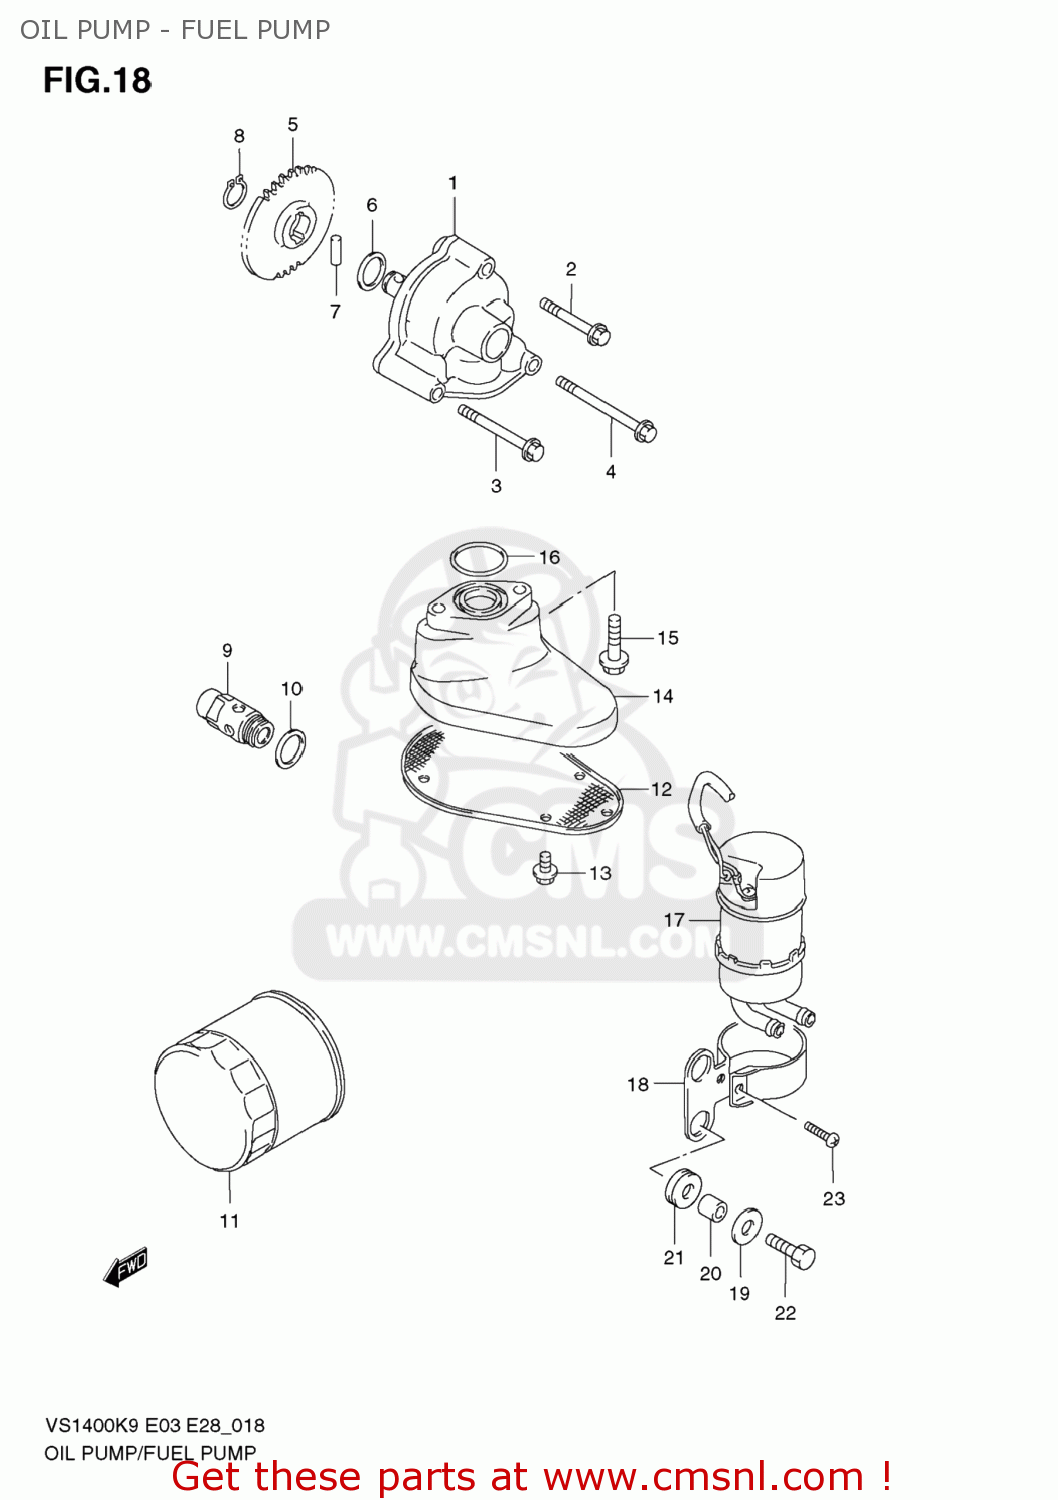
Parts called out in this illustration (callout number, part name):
1	PUMP ASSY,ENGINE OIL
2	BOLT
3	BOLT
4	BOLT
5	GEAR,OIL PUMP DRIVEN
6	SHIM(12X20X0.5)
7	PIN(5X18)
8	CIRCLIP,12 MM
9	VALVE ASSY,OIL RELIEF
10	GASKET(16X22X2) (NAS)
11	FILTER ASSY,EN
12	STRAINER,ENGINE OIL
13	BOLT
14	HOLDER,OIL STR
15	BOLT
16	O RING(D:3.1,ID:22.7)
17	PUMP ASSY,FUEL
18	BRACKET,FUEL PUMP
19	WASHER(6.5X20X1.6)
20	SPACER(6.5X10X9.4)
21	CUSHION
22	BOLT
23	SCREW
